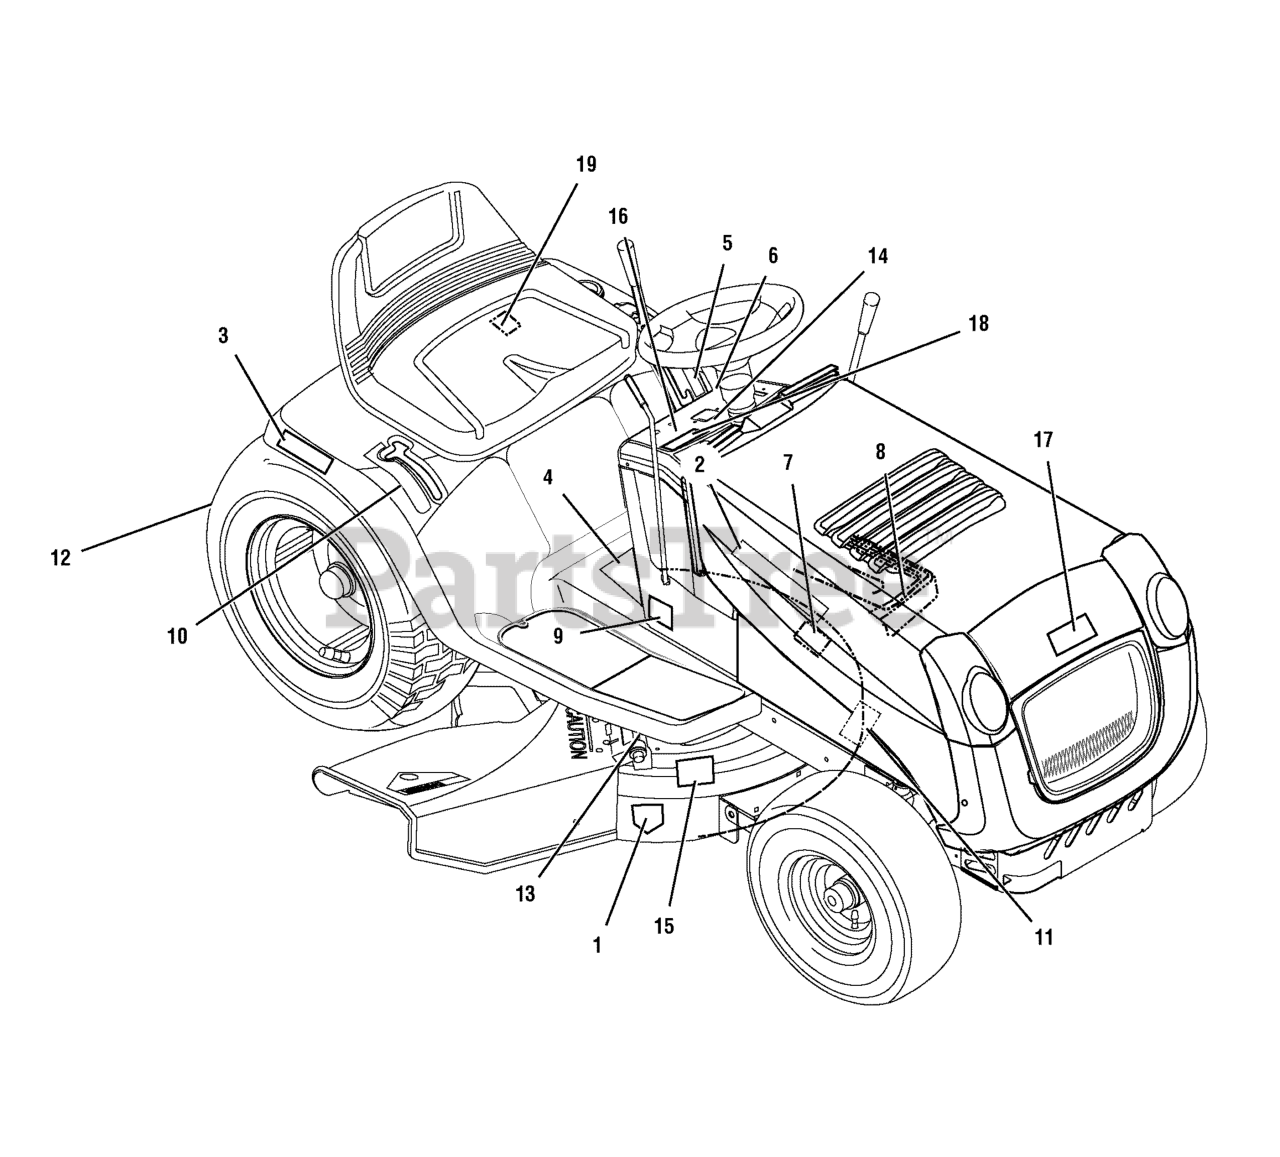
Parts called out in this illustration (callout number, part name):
1	DECAL, Cut Finger Symbols
2	DECAL, Performer R.H. & L.H.
3	DECAL,12.5/96 R.H. & L.H.
4	DECAL, Warning Export
5	DECAL, 7 Position Cut Height
6	DECAL, Deck Level
7	DECAL, No Step Export
8	DECAL, Brake/Clutch Export
9	DECAL, B&S Logo
10	DECAL, 5 Speed
11	DECAL, Heat Shield Warning
12	DECAL, Warning Load Limit Export
13	DECAL, Warning Pinch Point
14	DECAL, Dash/Symbols X-W Styles
15	DECAL, 100db Export
16	DECAL, Gas Gauge
17	DECAL, Beal Hood
18	DECAL, Hydro Drive
19	DECAL, Auto Drive Dump Valve
